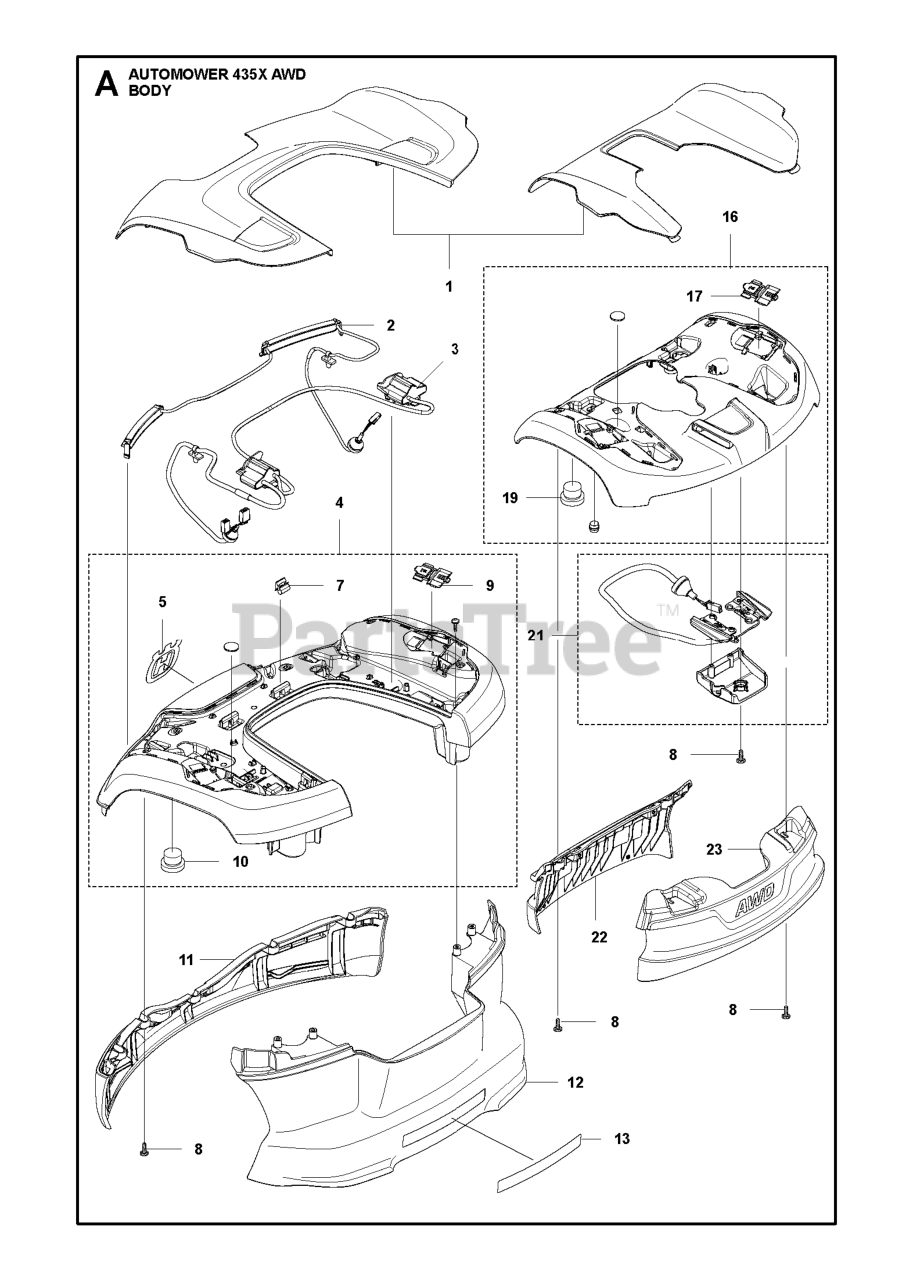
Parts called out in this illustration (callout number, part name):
2	Wires
3	Wires
4	Body
5	Decals
7	Clips
8	SCREW ITXPANT
9	Holders
10	CAP SNAPLOC
11	Bumpers
12	Bumpers
13	LABEL WARNING P15
16	Body
17	Holders
19	CAP SNAPLOC
22	Bumpers
23	Bumpers
